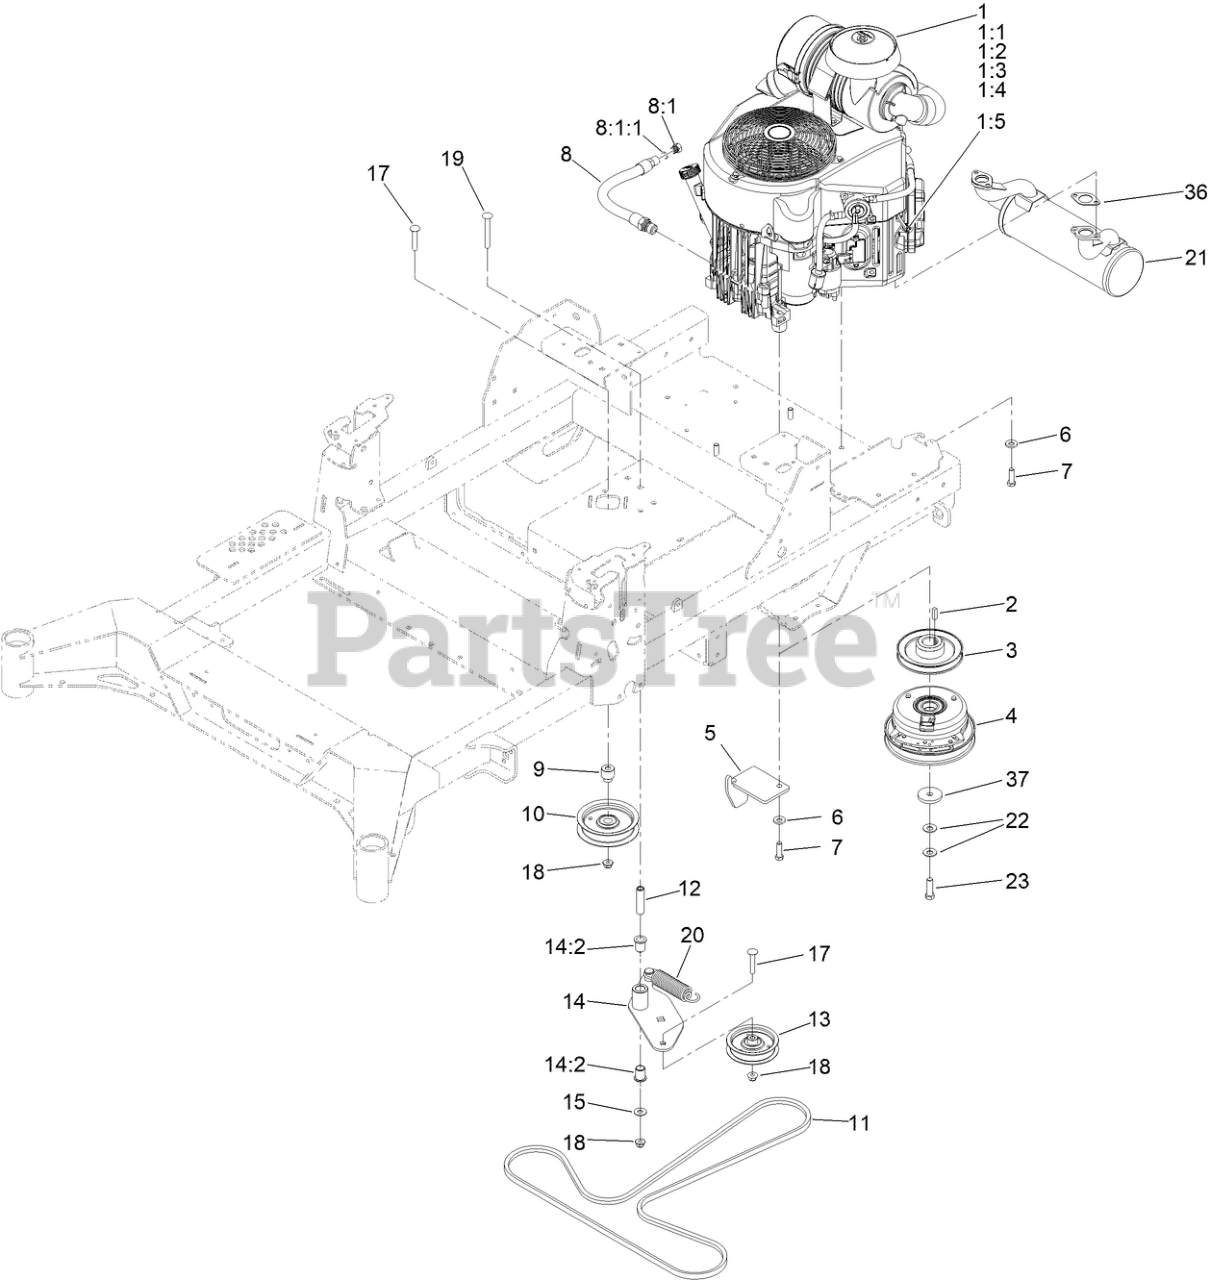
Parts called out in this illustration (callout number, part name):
1:1	FILTER-OIL
1:2	Filter-Fuel
1:3	ELEMENT-FILTER, AIR (INNER)
1:4	ELEMENT-FILTER, AIR (OUTER)
1:5	SPARK PLUG
3	SHEAVE (W/HUB)
4	CLUTCH 6.75, 105 FTLB, 1.125 DD
5	ANCHOR-CLUTCH
6	WASHER-BELLEVILLE
7	SCREW-HH
8	ENGINE OIL DRAIN HOSE ASM
8:1	PLUG-HH
8:1:1	O-RING
9	BUSHING-IDLER
10	PULLEY-IDLER, FLAT
11	BELT-V
12	BUSHING, IDLER PIVOT
13	PULLEY-IDLER, FLAT
14	IDLER ARM ASM
14:2	BUSHING-FLANGE
15	WASHER-FLAT
17	BOLT-CARRIAGE
18	NUT-HF, NI
19	SCREW-CARR
20	SPRING-EXTENSION
21	MUFFLER
22	WASHER-SPRING
23	SCREW-HH, W/LOCTITE
36	GASKET-EXHAUST
37	WASHER-CLUTCH
